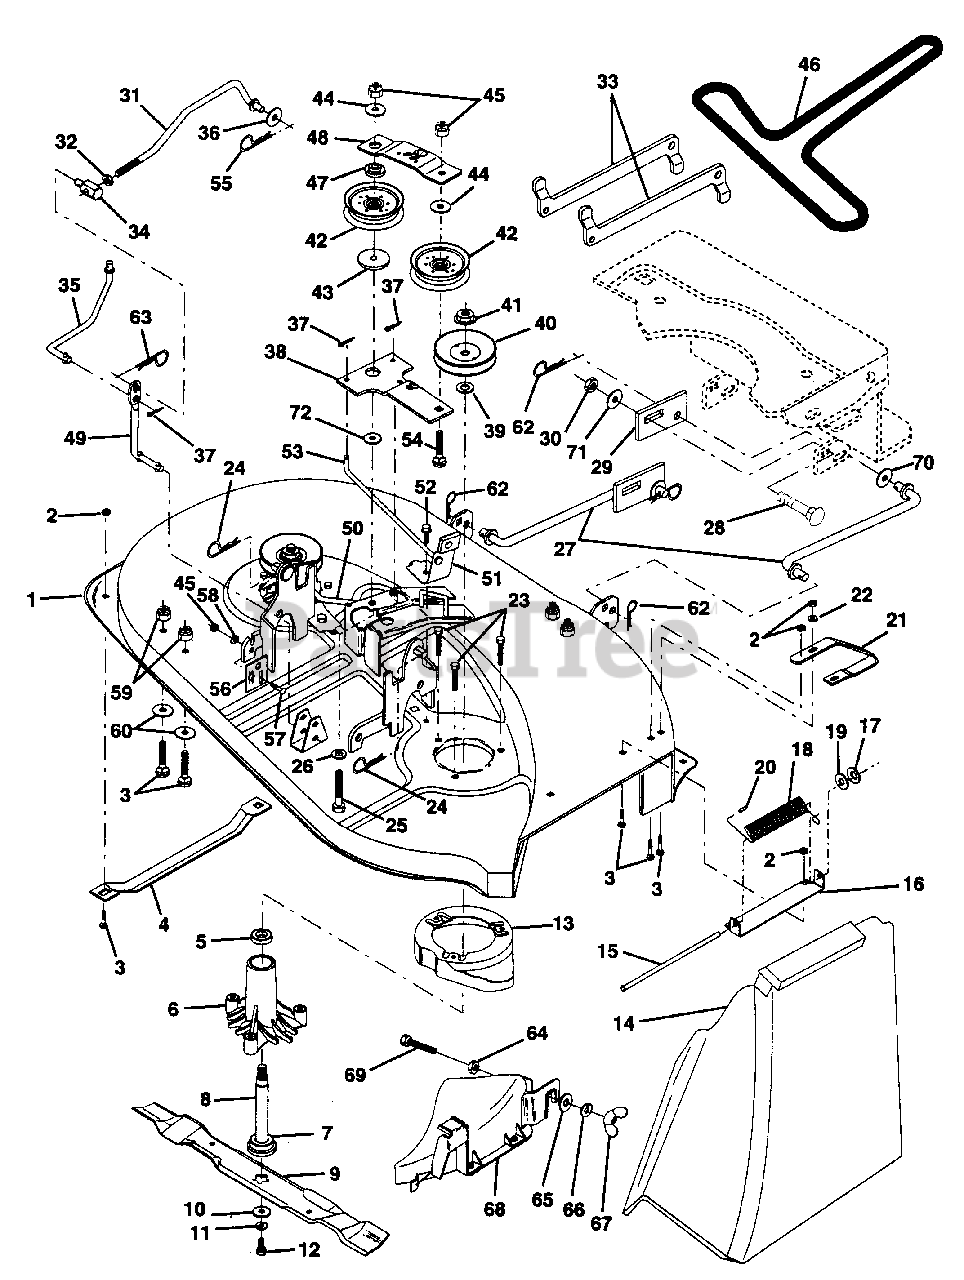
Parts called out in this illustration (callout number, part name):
1	Mower Deck Assembly
2	Nut, Lock Hx w/Ins 5/16-18
3	Bolt, Carriage 5/16-18 x 3/4
4	Runner, L.H.
6	Housing, Mandrel
7	Bearing
8	Shaft and Bearing Assembly, Mandrel (Inc.7)
10	Washer, Hardened
11	Washer, Lock 3/8
12	Bolt, Hex 3/8-24 x 1-1/4 Grade 8
13	Stripper, Mower, Vented
14	Shield, Deflector
16	Bracket Assembly, Deflector
18	Spring, Deflector
19	Washer 11/32 x 5/8 x 16 Gauge
22	Washer 11/32 x 3/4 x 16 Gauge
23	Screw Thdrol Hex Head Zinc MWR
24	Retainer, Spring
25	Bolt Hex 3/8-16 x 2-1/4
26	Washer 13/32 x 1 x 12 Gauge
27	Link Assembly, Front
28	Bolt RDHD SQNK 3/8 - 16 x 1
29	Plate Slide Link
30	Nut, Lock Hex w/washer 3/8 - 16
31	Clutch Rod, Primary
32	Nut, Hex, Jam 3/8-16
33	Arm, Suspension, Rear
34	Trunnion 3/8-16
35	Clutch Rod, Secondary
36	Washer 13/32 x 13/16 x 16 Gauge
37	Pin, Cotter 3/32 x 3/4
38	Idler Arm
39	Washer .150 Thick
40	Pulley, Mandrel
41	Nut, Flangelock 9/16
42	Pulley, Flat Idler
43	Spacer, Retainer
44	Washer 13/32 x 1 x 12 Gauge
45	Nut, Crownlock 3/8-16
46	Belt
47	Spacer, Idler Arm
48	Stiffener, Idler Arm
50	Rod, Brake, L.H.
51	Brake Assembly
52	Screw, Hex Washer Head, Thd., Roll. 5/16-18 x 3/4
53	Rod, Brake, R.H.
54	Bolt, Carriage 3/8-16 x 1-3/4 Grade 5
55	Spring, Retainer
56	Adjustment Plate, Rear Link, L.H.
57	Bolt, Carriage 3/8-16 x 1
58	Washer 13/32 x 3/4 x 12 Gauge
59	Locknut, Hex, with Washer Insert 5/16-18
60	Washer 11/32 x 11/16 x 12 Gauge
62	Retainer Spring
63	Retainer Spring
64	Nut, Centerlock 3/8 - 16
65	Washer 13/32 x 1-1/4 x 16 Ga.
66	Washer Lock 3/8
68	Cover Asm Mulching
69	Bolt 3/8 - 16 x 1-1/4
70	Washer 1/2 x 1-1/4 x 16 Ga.
71	Washer Flat 13/32 x 1 x 10 Ga.
72	Washer Hardened
